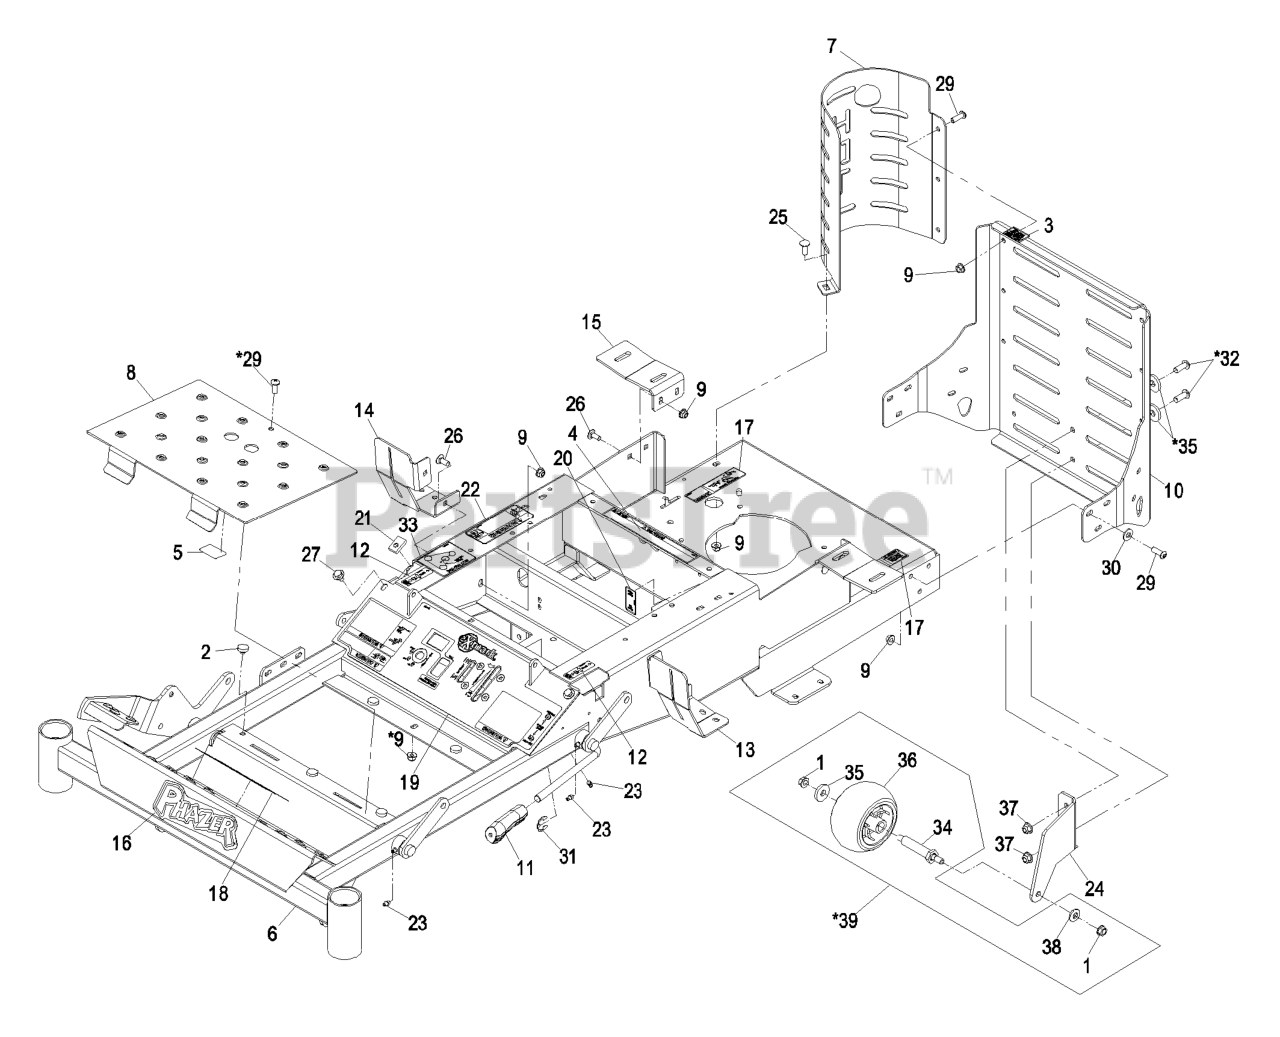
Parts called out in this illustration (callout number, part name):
1	NUT-HHF, WHIZ
4	DECAL-BATTERY
5	DECAL-GUARD
6	ASM,PHAZER FRAME W/DECALS
7	GUARD-MUFFLER
9	NUT-HF, NI
10	REAR GUARD ASM
11	GRIP-LEVER, BRAKE
12	DECAL-CONTROL, MOTION
13	MOUNT-TANK, FUEL (LH)
14	MOUNT-TANK, FUEL (RH)
15	BRACKET-FUEL TANK, REAR
16	DECAL,PHAZER
17	DECAL,ZT DUMP
18	DECAL-SLOPE, DANGER
19	DECAL,CONSOLE
20	DECAL-RELAY
21	STOP-MOTION
22	DECAL-DEVICES, ROTATING
23	FITTING-GREASE
24	BRACKET,REAR TILT
25	BOLT-CARR
26	SCREW-CARR
27	SCREW-HHF
29	SCREW-HSBH
30	WASHER-PLAIN
31	E-RING
32	SCREW-HSBH
33	DECAL,BELT ROUTING
35	WASHER
36	ROLLER-SCALP, ANTI
37	NUT-HF, NI
38	WASHER-BELLEVILLE
